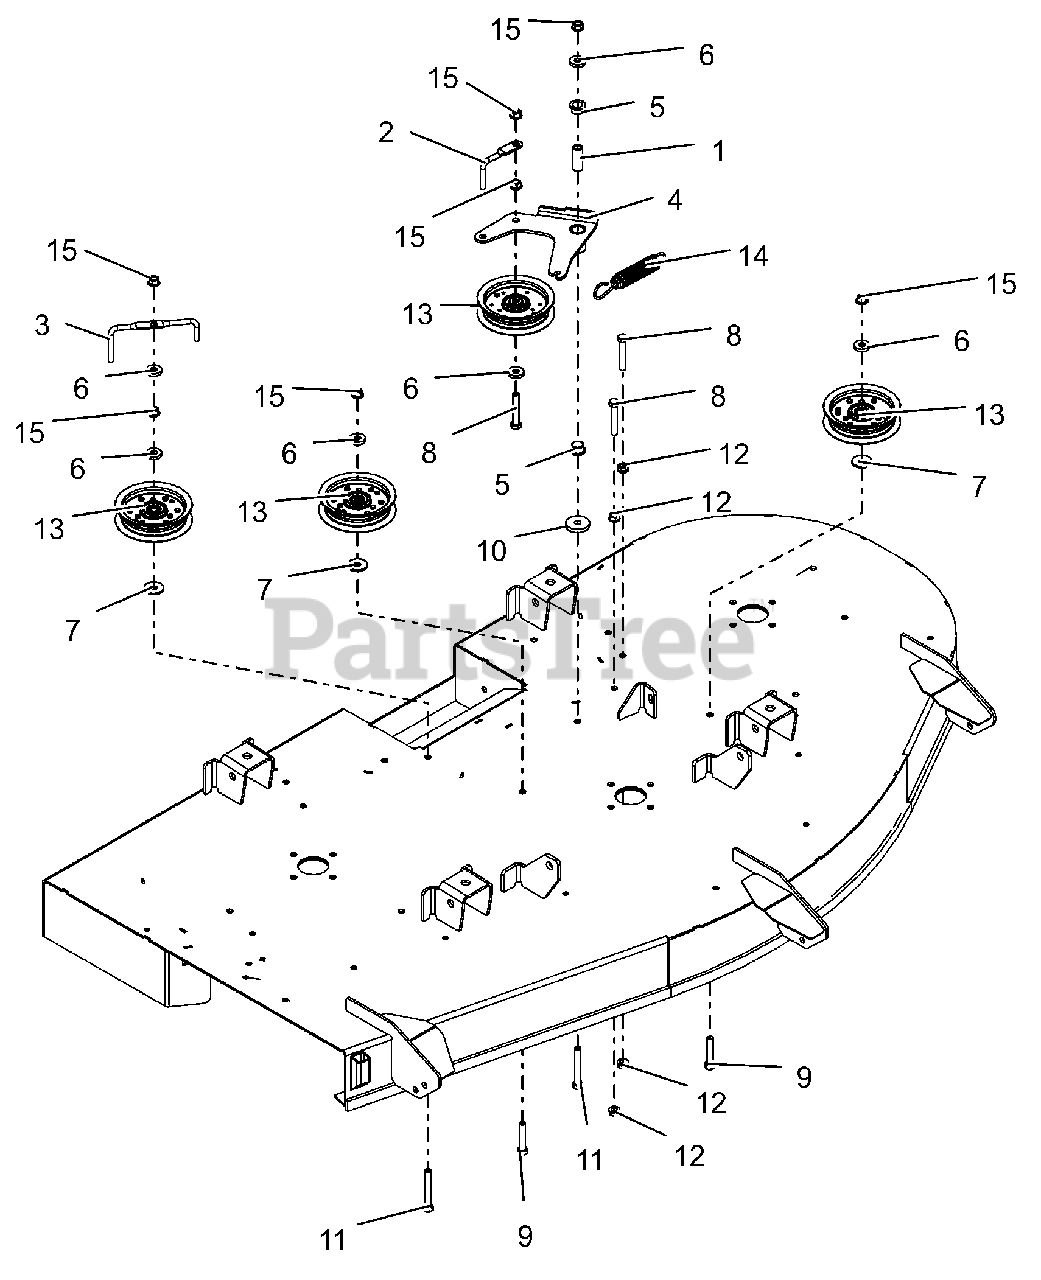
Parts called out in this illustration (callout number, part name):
1	SPACER, .375IDX.625ODX1.66 PM
2	WIREFORM, BELT FINGER
3	WIREFORM, BELT FINGER
4	WLDMT, IDLER ARM-42"
5	BSHG-FLG, .625X.750X.500X1.00
6	WSHR, FLT .406X1.00X.188 ZCC
7	WSHR FL STL .406X1.25X.10ZC120
8	BLT,HEX .38-16X2.25 G5 ZCC
9	BLT,HEX .38-16X2.00 G5 ZCC
10	WSHR, FLT .406X1.50X.245 ZCC
11	BLT, HEX .38-16X2.75 G5 ZCC
12	NUT, SPNLK-FLG .38-16 G5 ZCC
13	ASM, IDLER 4"
14	SG-TENS .135X.98X6.0 WLD 62
15	NUT-LK-CTR-FLG .375-16 GF ZCC
